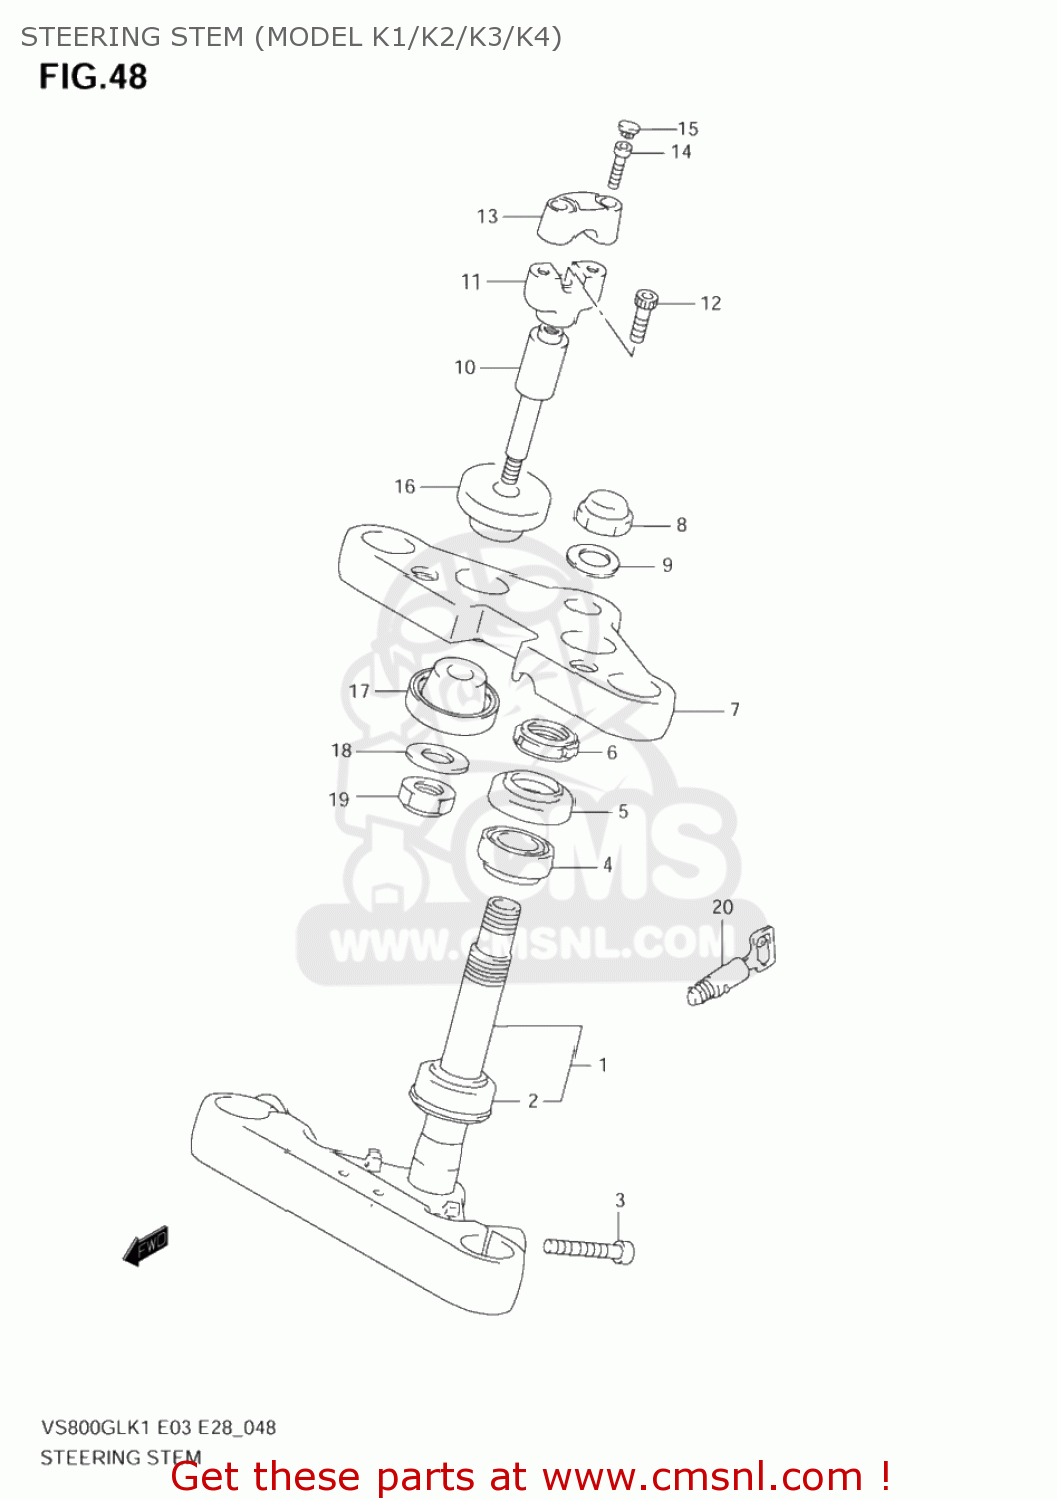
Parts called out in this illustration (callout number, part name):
1	STEM,STEERING
2	BEARING(30X55X17)
3	BOLT
4	BEARING(25X47X15)
5	SEAL,STEERING UPR DUST
6	NUT,STEERING STEM(25X44X10)
7	BRACKET,UPR
8	NUT,CAP
9	WASHER(22.5X32X1.6)
10	STAY,HANDLE
11	HOLDER,HANDLE LWR
12	BOLT
13	HOLDER,HANDLE UPR
14	BOLT
15	CAP(OD:14.5)
16	DAMPER,RUBBER
17	CUSHION,RUBBER UNDER
18	WASHER
19	NUT
20	LOCK SET,STEERING
